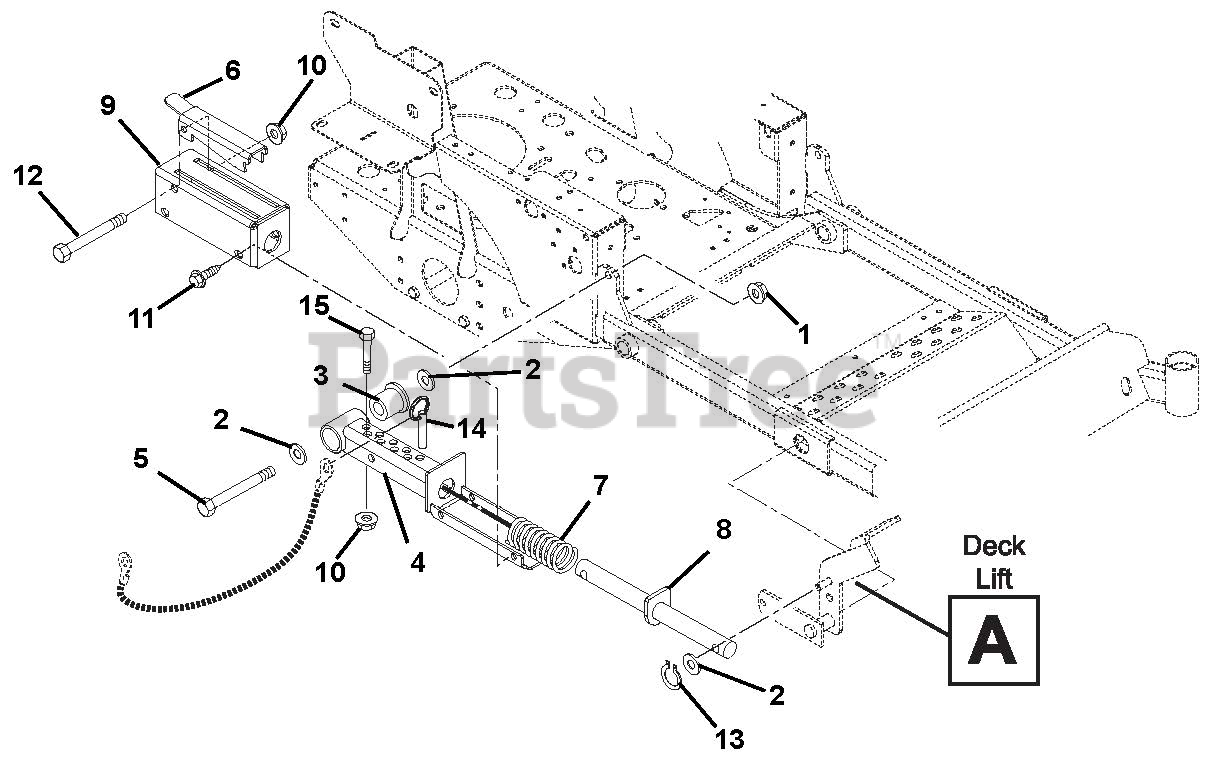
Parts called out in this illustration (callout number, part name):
1	Nut, Locking Top Flange .50-13
2	Washer, Flat Steel .531 x 1.25 x .10
3	Bearing, Pedestal Powdered Metal
4	Weldment, Mechanical Lift
5	Bolt, Hex .50-13 x 3.75 Grade 5
6	Lock-Up, Mechanical Lift
7	Spring, Compression 1.13 x 1.48 x 5.10
8	Weldment, Mechanical Lift Shaft
9	Weldment, Mechanical Lift Cover
10	Nut, Nyloc Flange 3/8-16
11	Screw, Tapping .38-16 x .50 Hex Washer Head
12	Bolt, Hex .38-16 x 3.25 Grade 5
13	Ring, Retaining External .50 x .05
14	Pin, Spring Ball .375 O.D. x 1.50
15	Bolt, Hex .38-16 x 2.00 Grade 5
